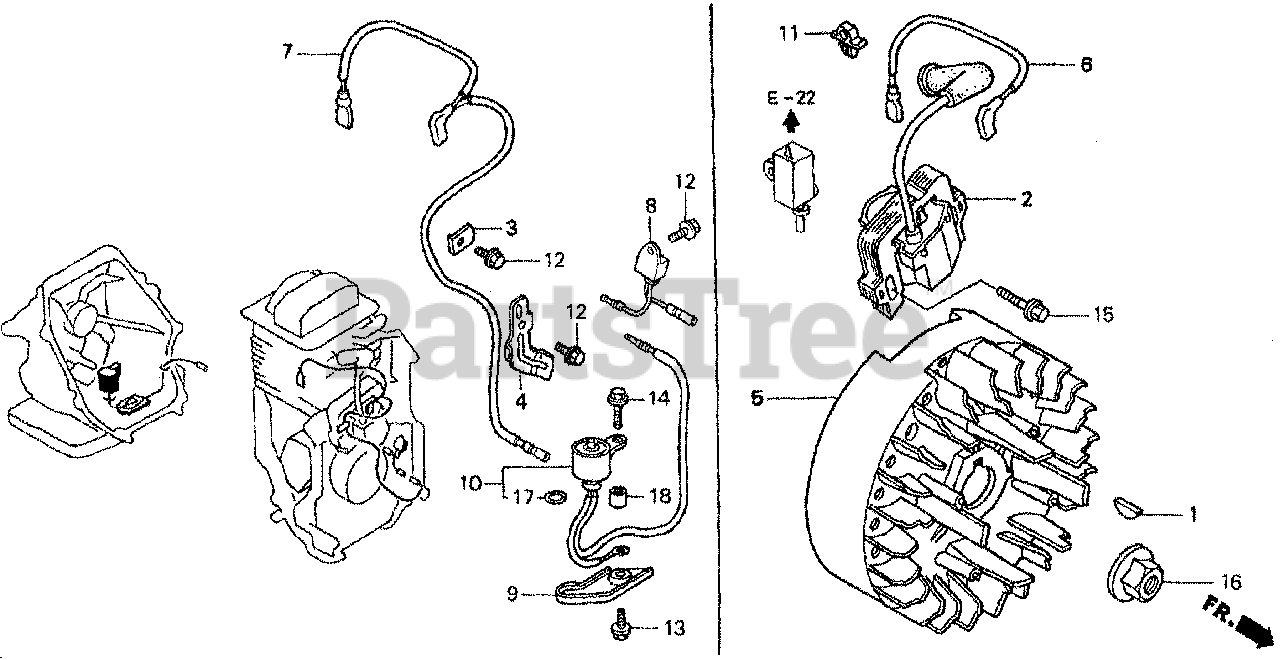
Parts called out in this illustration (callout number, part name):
1	KEY, SPECIAL WOODRUFF (25X18)
2	COIL ASSY., IGNITION
3	CLAMP, STOP SWITCH WIRE
4	CLAMP, WIRE
7	WIRE, STOP SWITCH
8	ALERT UNIT, OIL
9	PROTECTOR, SWITCH
10	SWITCH, OIL LEVEL
11	HOLDER, STOP SWITCH WIRE
12	BOLT, FLANGE (6X12) (CT200)
13	BOLT, FLANGE (6X14)
14	BOLT, FLANGE (6X28)
15	BOLT, FLANGE (6X20) (CT200)
16	NUT, SPECIAL (14MM)
17	O-RING (11.8X2.4)
18	COLLAR (6.6X13.8X14.5)
